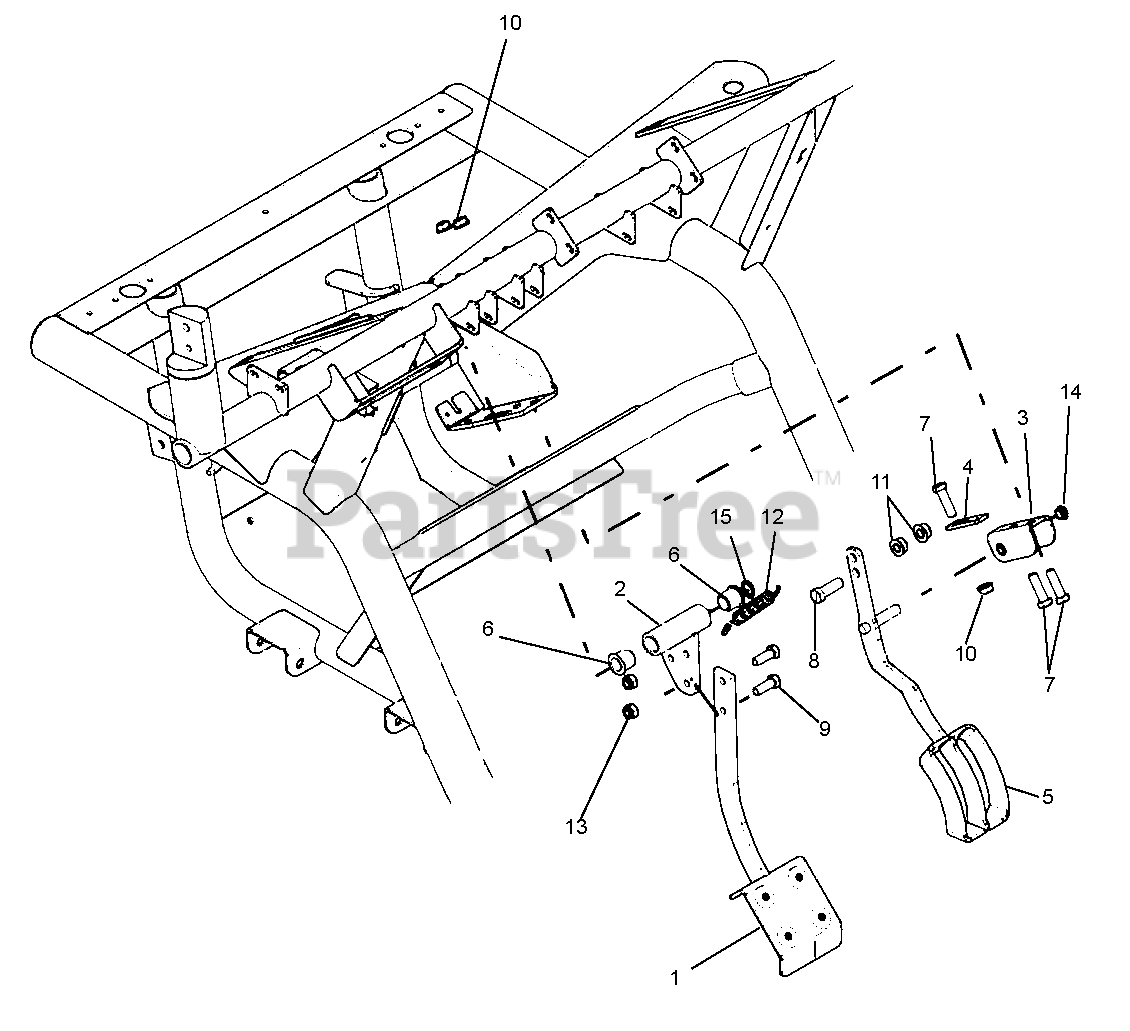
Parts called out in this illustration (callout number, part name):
1	BRAKE PEDAL ASSEMBLY
2	BRAKE PEDAL PIVOT WELDMENT
3	GAS PEDAL MOUNT
4	GAS PEDAL ADJUSTMENT PLATE
5	WELDMENT, GAS PEDAL
6	BUSHING, 3/4OD X 5/8ID X 3/4 FLG HD
7	BOLT, HEX .31-18 X 1.25 GR5 YWZC
8	BOLT, HEX 3/8-16 X 1 1/4 GR5 YWZC
9	BOLT, HEX .31-18 X 1.00 GR5 YWZC
10	NUT, LOCKING TOP FLANGE .31-18 YWZC
11	NUT, LOCKING TOP FLANGE .38-16 YWZC
12	SPRING, EXTENSION .5OD .075W 2.75LG
13	NUT, LOCKING NYLON .312-18 YWZC
14	BUSHING NYLON 3/8 ID (SNAP IN)
15	SNAP RING, .625 X .035 EXT
